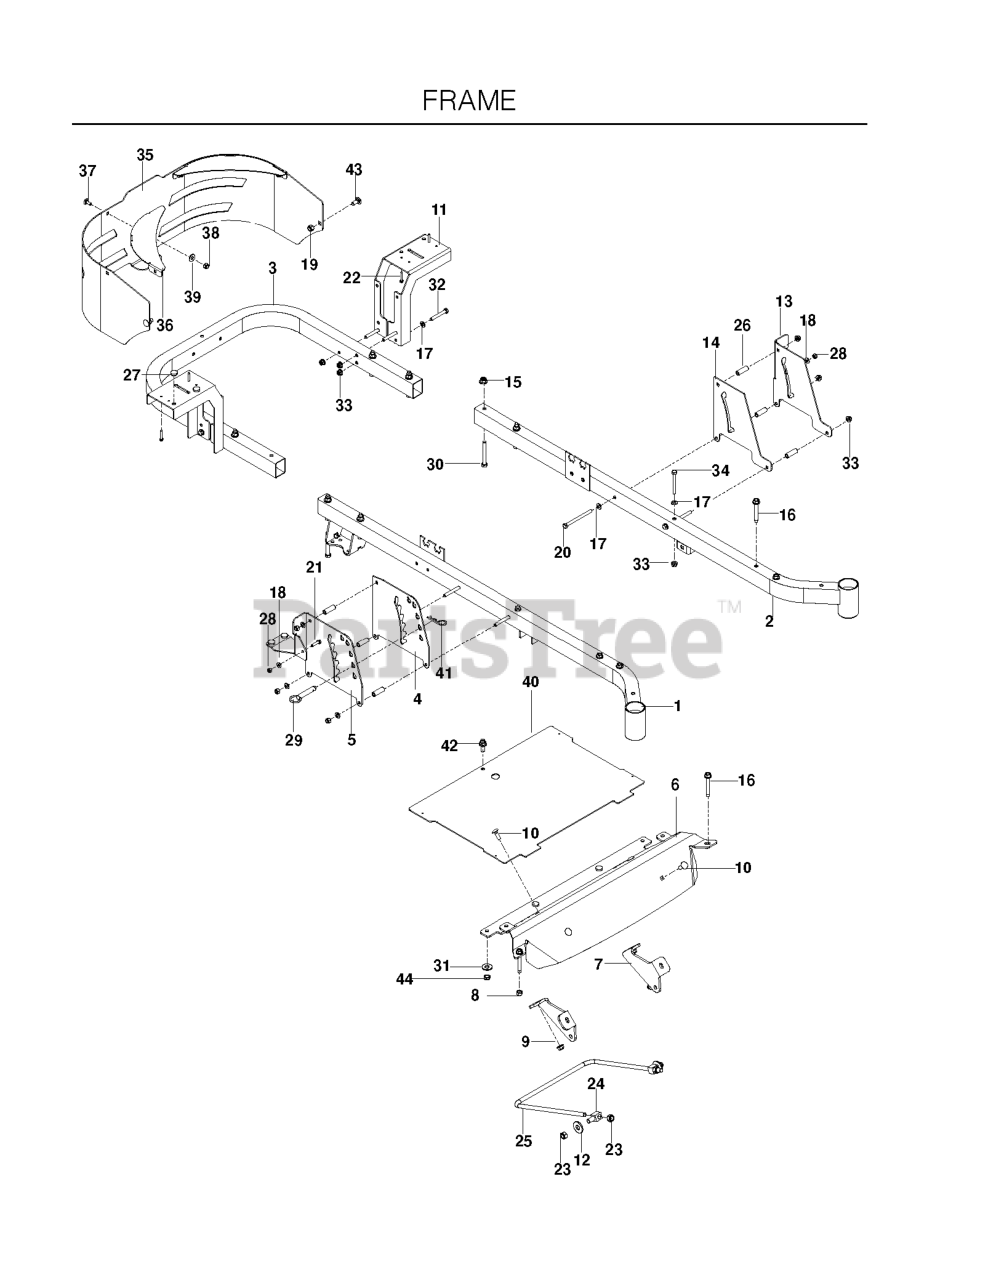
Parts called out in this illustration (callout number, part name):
1	FRAME, RT, ORANGE
2	FRAME, LT, ORANGE
3	FRAME TUBE, REAR, ORANGE
4	PLATE, DECK HEIGHT, BLK EZ
5	PLATE, DECK HEIGHT, BLACK
6	FOOT REST WIDE ORG
7	MOUNT, STRUT, RT, BLK
8	MOUNT, STRUT, LT, BLK
9	NUT 3/8-16 HEX FLG NYLOC ZD
10	RHSNB 3/8C X 1
11	SUPPORT, FENDER, BLACK
12	WASH USS FLAT 1/2
13	PLATE, OUTER BRAKE, BLACK
14	PLATE, BRAKE LATCH, BLACK
15	NUT 3/8-16 HEX FLG NYLOC ZD
16	ENGINE BOLT, SPECIAL
17	FLAT WASHER 5/16 SAE
18	WASHER 1/4 SAE
19	NUT 5/16 NYLOC
20	HCS 5/16C X 4
21	HCS 1/4C X 1
22	SCR #10-12X1-1/2HEX WASH HD ZD
23	7/16-14 HEX NUT W/NYL RING ZD
25	LINK, FRONT SUSP.
26	SPACER, .334 ID X .5 OD X 1.5
27	GROMMET, BUMPER
28	NUT.1/4-20.HEX.NYLOC.ZD
30	HCS 3/8C X 3
31	WASHER 3/8 FLAT
33	5/16-18 NYLOC FLANGE NUT
34	HCS 5/16C X 2-3/4
35	GUARD, REAR, ORANGE
36	SUPPORT, CORNER, ORANGE
37	RHSSNB, 1/4-20X5/8
38	NUT.1/4-20.HEX.NYLOC.ZD
39	WASHER 1/4 FLAT
40	PLATE, FOOT W/DECALS EZ
41	HAIRPIN #4
42	HHFS 5/16-18 X 3/4
43	BOLT 5/16C X 3/4" CARRIAGE
44	NUT HEX 3/8-16 NYLON, THIN
